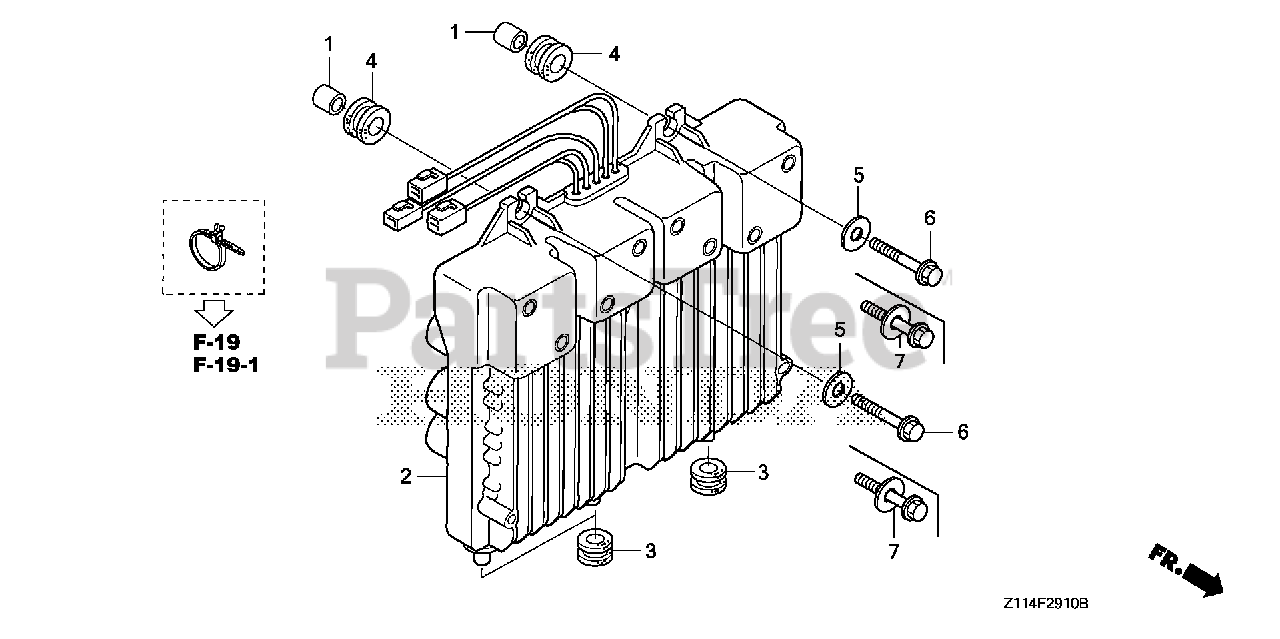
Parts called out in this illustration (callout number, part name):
1	COLLAR, IN. JOINT
2	INVERTER UNIT
3	CUSHION, TANK RUBBER
4	RUBBER, INVERTER UNIT
5	WASHER, PLAIN (6MM)
6	BOLT, FLANGE (6X25)
7	BOLT-WASHER (6X25)
